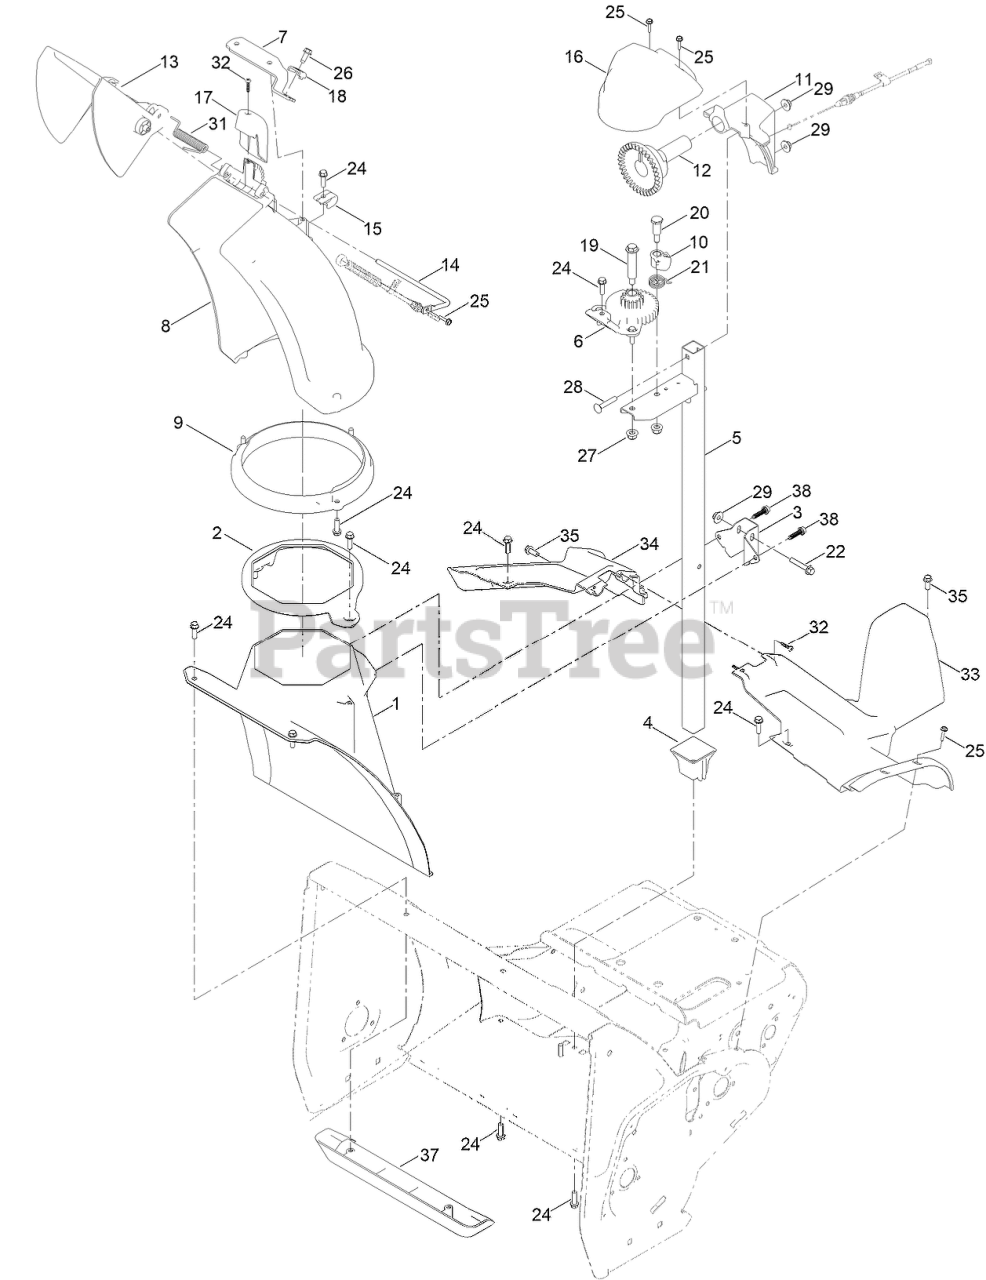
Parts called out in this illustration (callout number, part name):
1	CHUTE-LOWER
2	GUIDE-CHUTE
3	BRACKET-POST, SUPPORT (CHUTE)
4	RETAINER- POST, CHUTE
5	POST-CHUTE
6	GEAR-CHUTE
7	BRACKET-CABLE
8	CHUTE-DISCHARGE
9	RING-CHUTE
10	LATCH-CHUTE
11	MOUNT-GEAR, CHUTE
12	GEAR-FACE
13	DEFLECTOR-CHUTE
14	ROD-DEFLECTOR
15	GUIDE-CABLE
16	COVER-GEAR, CHUTE
17	CHUTE-COVER
18	CLAMP-CABLE
19	BOLT-SHOULDER
20	SCREW-SHOULDER
21	SPRING-TORSION, LATCH (CHUTE)
22	SCREW-HHF
24	SCREW-HWH
25	SCREW-HWH
26	SCREW-HWH
27	NUT-HF, NI
28	SCREW-CARR
29	NUT-HF
31	SPRING-TORSION
32	SCREW-PPH
33	SHROUD-UPPER, LH
34	SHROUD-LOWER, RH
35	SCREW-HWH
37	KICKER-HOUSING
38	SCREW-FLANGE, PLASTIC
